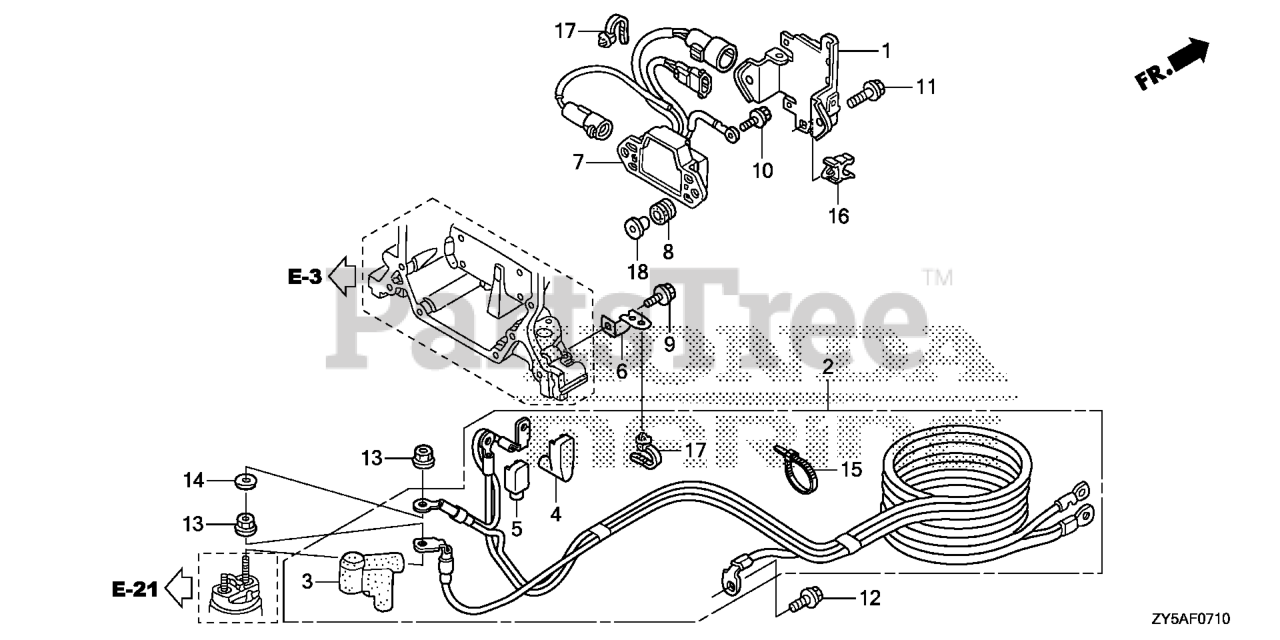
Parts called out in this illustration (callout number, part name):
1	BRACKET A, CONNECTOR
2	CABLE ASSY., STARTER
3	COVER, STARTER TERMINAL
4	COVER B, TERMINAL (L)
5	COVER B, TERMINAL
6	BRACKET B, CABLE
7	RELAY ASSY., POWER TILT
8	GROMMET, RELAY
9	BOLT, FLANGE (6X14) (CT200)
10	BOLT, FLANGE (6X12)
11	BOLT, FLANGE (6X22)
12	BOLT, FLANGE (8X18)
13	NUT-WASHER (8MM)
14	WASHER, PLAIN (8MM)
15	BAND, WIRE (165MM) (BLACK)
16	CLIP, FUEL TUBE (14) (NOT AVAILABLE)
17	CLIP, HARNESS BAND (145MM) (BLACK)
18	COLR, CDI UNIT CASE
18	COLLAR, MODULE IGNITION CONTROL CASE (CDI)
